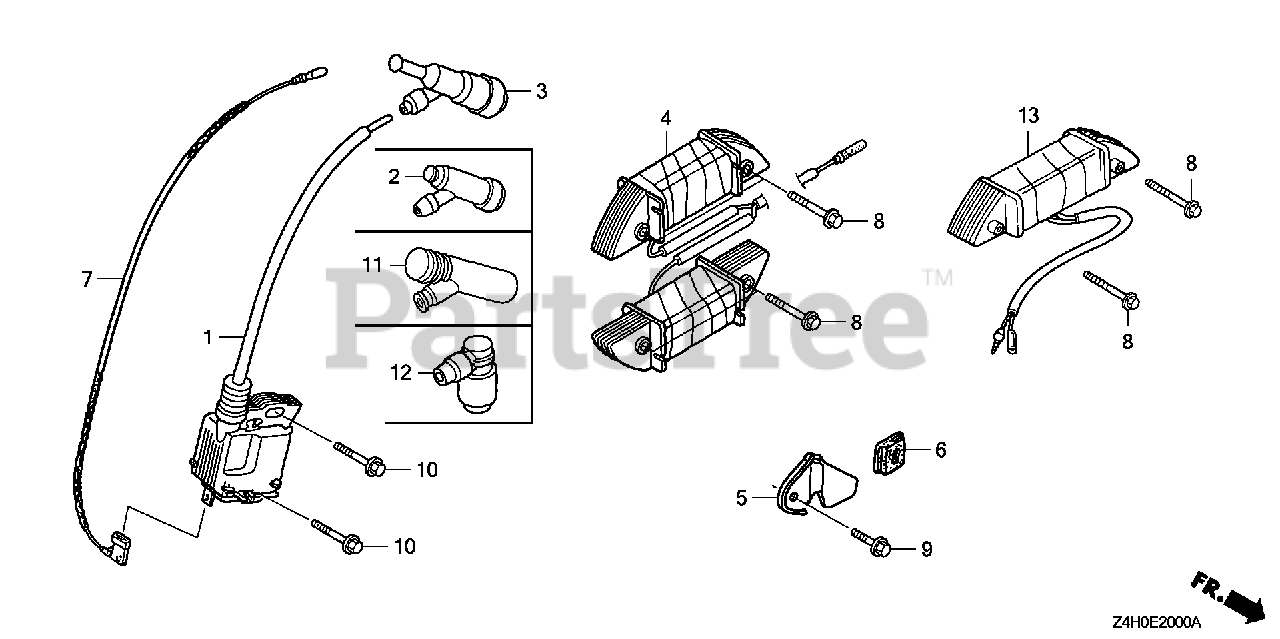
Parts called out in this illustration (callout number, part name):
1	COIL ASSY., IGNITION (TEC)
3	CAP ASSY., NOISE SUPPRESSOR (NGK)
3	CAP ASSY., NOISE SUPPRESSOR (TEC)
7	WIRE, STOP SWITCH (370MM)
10	BOLT, FLANGE (6X25) Use up to Engine SN 2056819.
